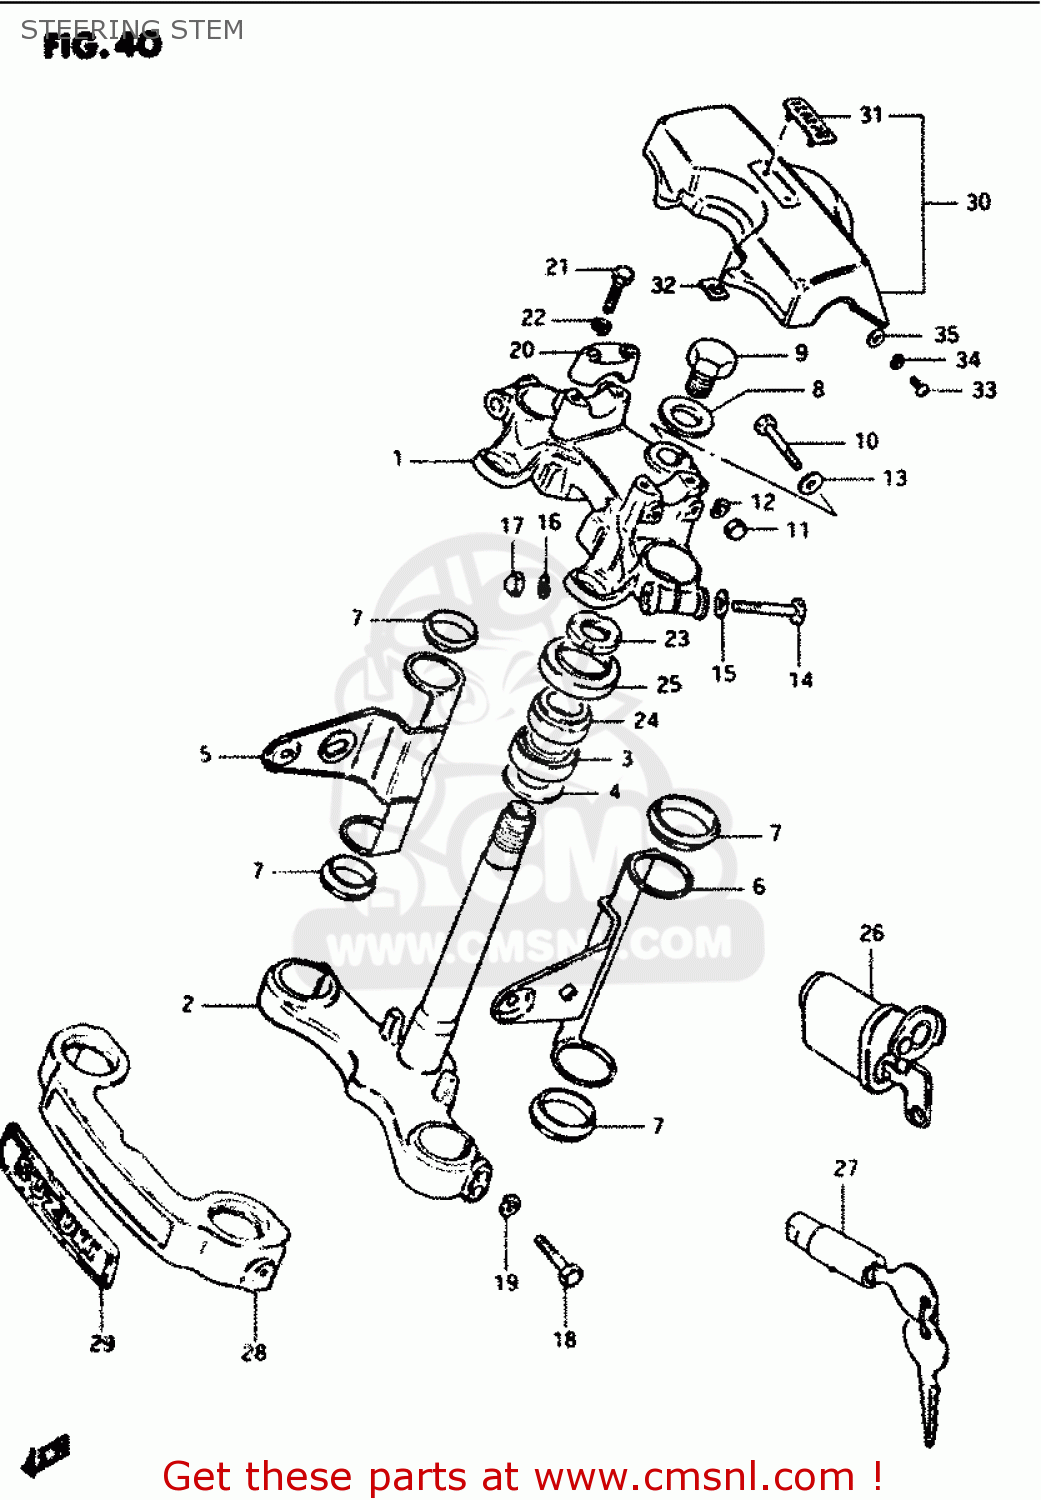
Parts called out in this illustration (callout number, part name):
1	HEAD,STEERING STEM
2	STEM,STEERING
3	BEARING
4	WASHER,THRUST
5	BRACKET,HEADLAMP,RIGHT
6	BRACKET,HEADLAMP,LEFT
7	CUSHION,HEADLAMP BRACKET
8	WASHER,STEERING STEM
9	NUT,STEM HEAD
10	BOLT 8X50
11	NUT
12	LOCK WASHER
13	WASHER
14	BOLT 10X55
15	WASHER
16	WASHER,LOCK,10
17	NUT, LOWER LH
18	BOLT
19	LOCK WASHER
20	HOLDER,HANDLE(BLACK)
21	BOLT
22	LOCK WASHER
23	NUT,STEERING STEM
24	TAPER,ROLLER BEARING
25	DUST SEAL,STEERING UPR
26	LOCK ASSY, STEERING (NEIMAN TYPE EXECUTE
27	LOCK ASSEMBLY,STEERING (NEI
28	COVER,FRONT FORK
29	EMBLEM,FRONT FORK COVER
30	PAD,HANDLEBAR
31	EMBLEM,HANDLE COVER PAD
32	NUT
33	SCREW
34	WASHER,LOCK
35	WASHER,5MM
